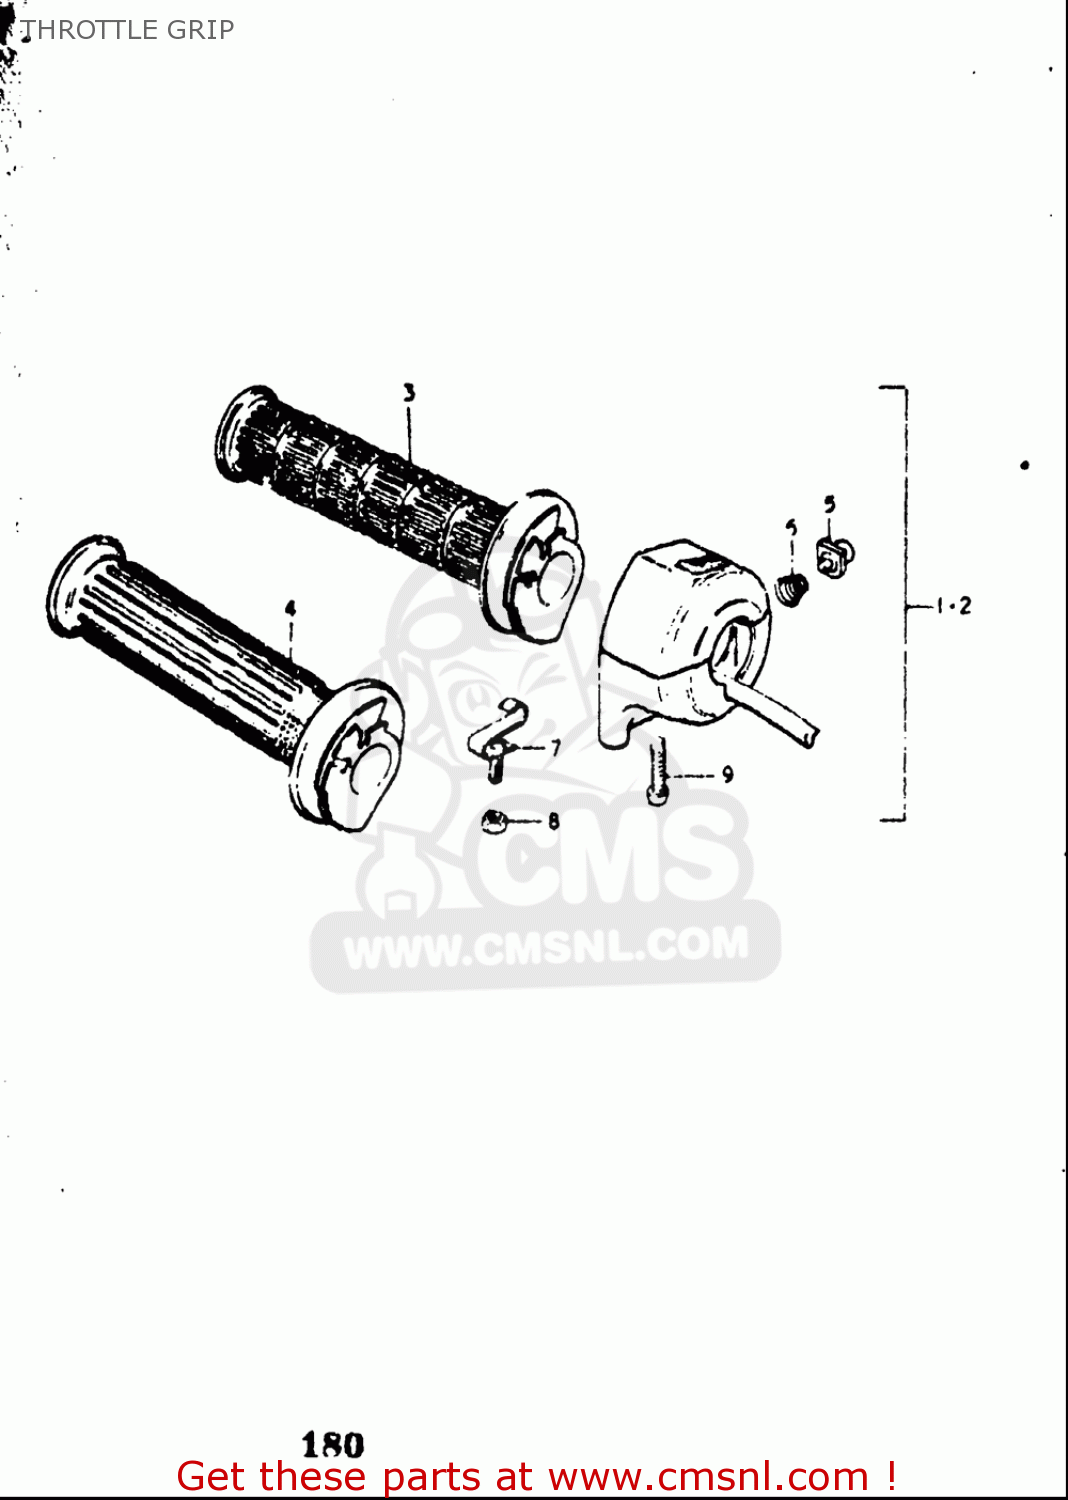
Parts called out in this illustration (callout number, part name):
3	GRIP,THROTTLE
4	GRIP,THROTTLE
5	BUTTON
6	SPRING
7	ADJUSTER, THROTTLE
8	NUT
9	SCREW
